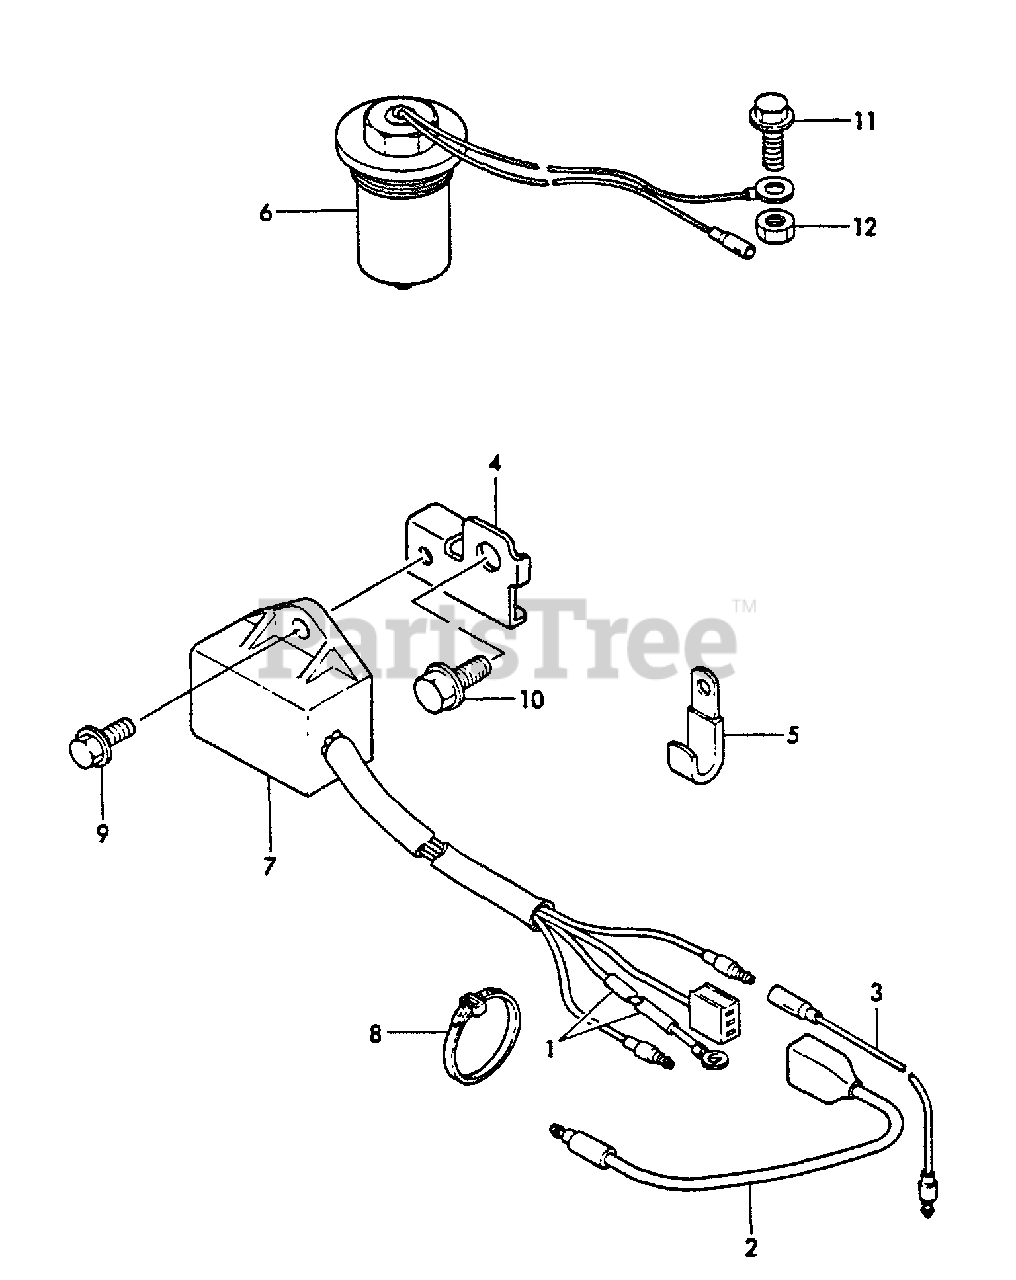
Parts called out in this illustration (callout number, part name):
1	TUBE, INSULATOR
2	WIRE
3	WIRE, SENSOR UNIT
4	STAY, SENSOR UNIT
5	CLAMP
6	SENSOR, OIL LEVEL
7	SENSOR, OIL
8	CLAMP
9	BOLT - 6X12 -- PLATED
10	BOLT - 8X14 -- PLATED
11	BOLT - 6X16 -- PLATED
12	LOCKNUT - 6 -- PLATED
